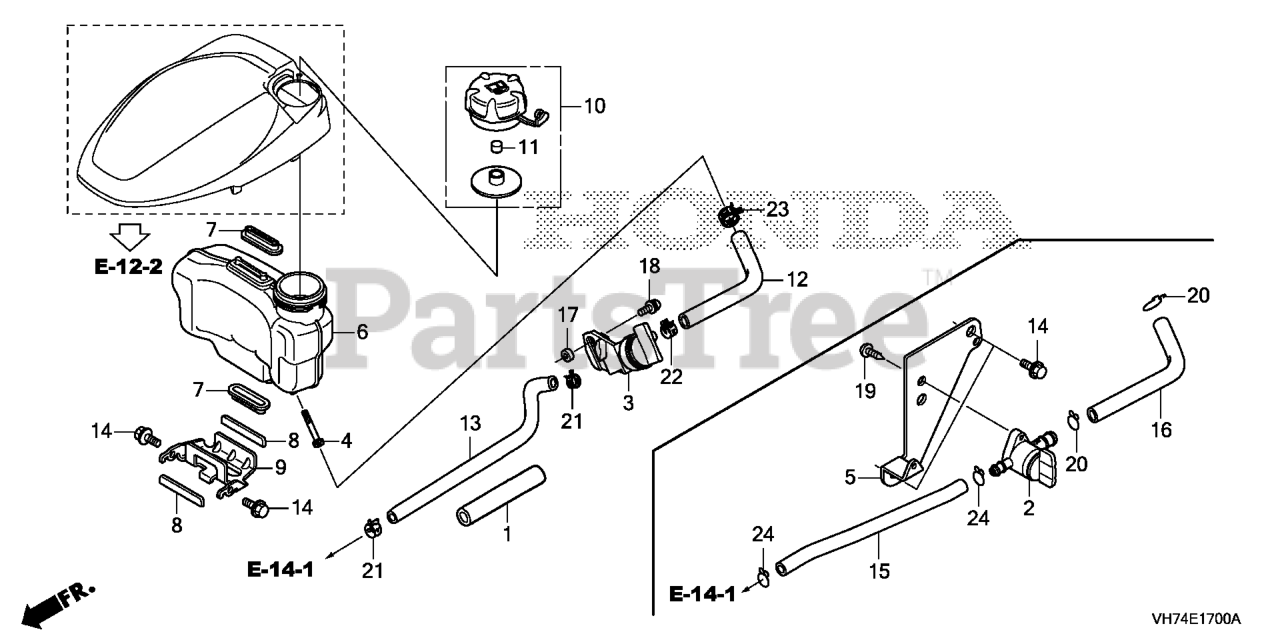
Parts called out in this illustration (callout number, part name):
2	PETCOCK ASSY.
4	FILTER, FUEL
5	STAY, PETCOCK
6	TANK, FUEL
7	RUBBER A, TANK MOUNTING
8	RUBBER B, TANK MOUNTING
9	STAY, FUEL TANK
10	CAP ASSY., FUEL TANK
11	SPONGE, FUEL CAP BREATHER
14	BOLT, FLANGE (6X14)
15	TUBE, FUEL (4.5X110)
16	TUBE, FUEL (7.3X160)
19	SCREW, TAPPING (5X12) (PO)
20	CLIP, TUBE (B12.5)
24	CLIP, TUBE (C9)
